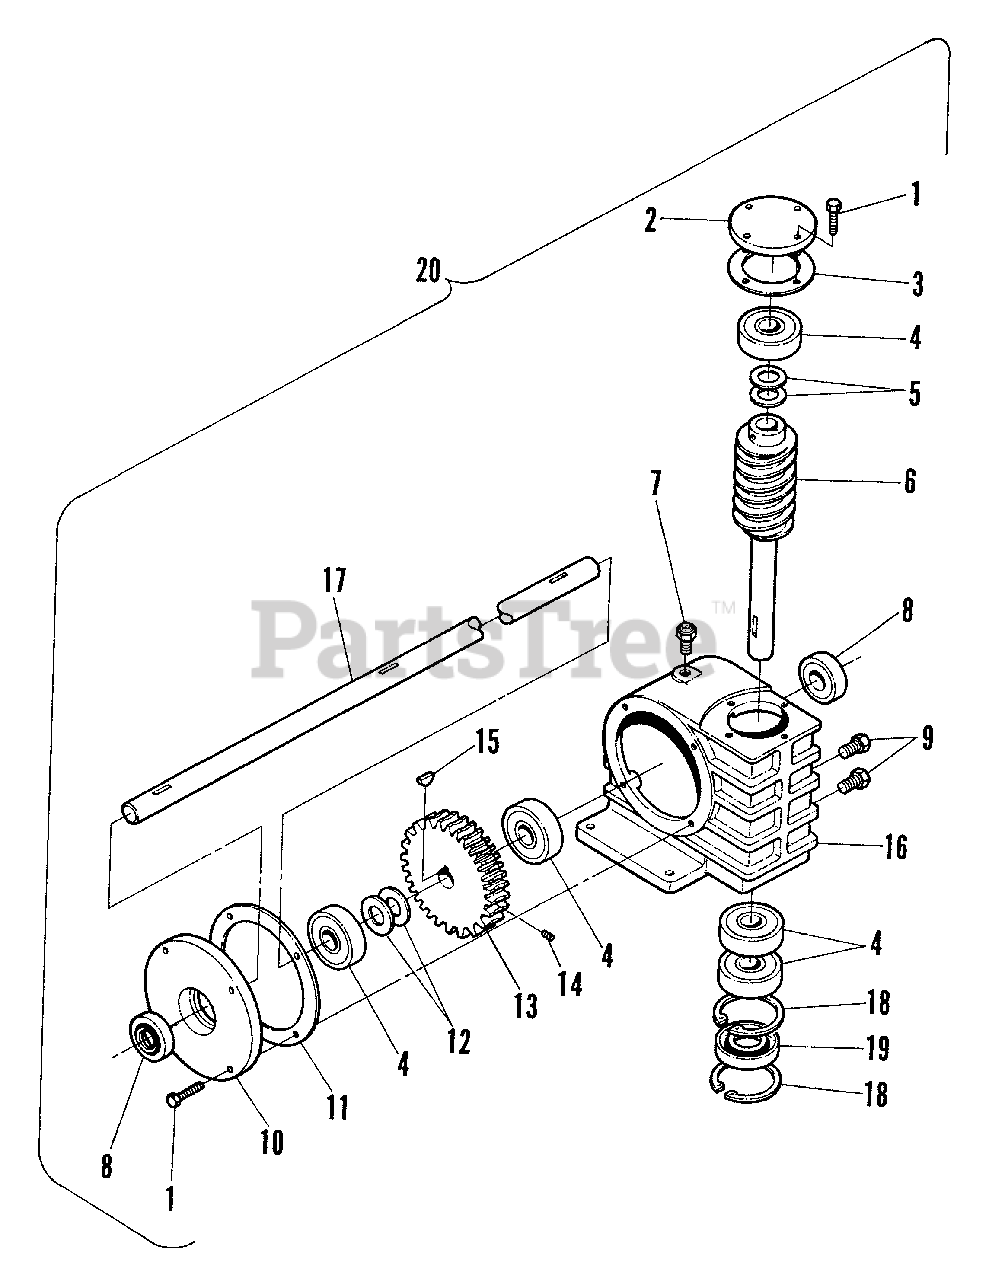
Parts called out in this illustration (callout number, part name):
1	SCREW, 1/4-20 x 5/8" Hex Head Cap, Grade 5
2	COVER, Input w/Bearing (77324)
3	GASKET, Input
4	BEARING
5	SHIMS, 5/8 x 7/8 x .010
6	ASSEMBLY, Worm (Dalton)
7	BREATHER
8	SEAL, Output Shaft
9	PIPE PLUG, 1/8-27
10	COVER, Output w/Bearing (77324)
11	GASKET, Output
12	SHIMS, 5/8 x 7/8 x .005
14	SCREW, 1/4-20 x 3/8" Socket Head Set
15	KEY, 5/405 Woodruff
16	GEAR CASE
17	SHAFT, Output
18	RING, Internal Snap
19	SEAL, Input
20	GEARBOX, Complete Assembly
